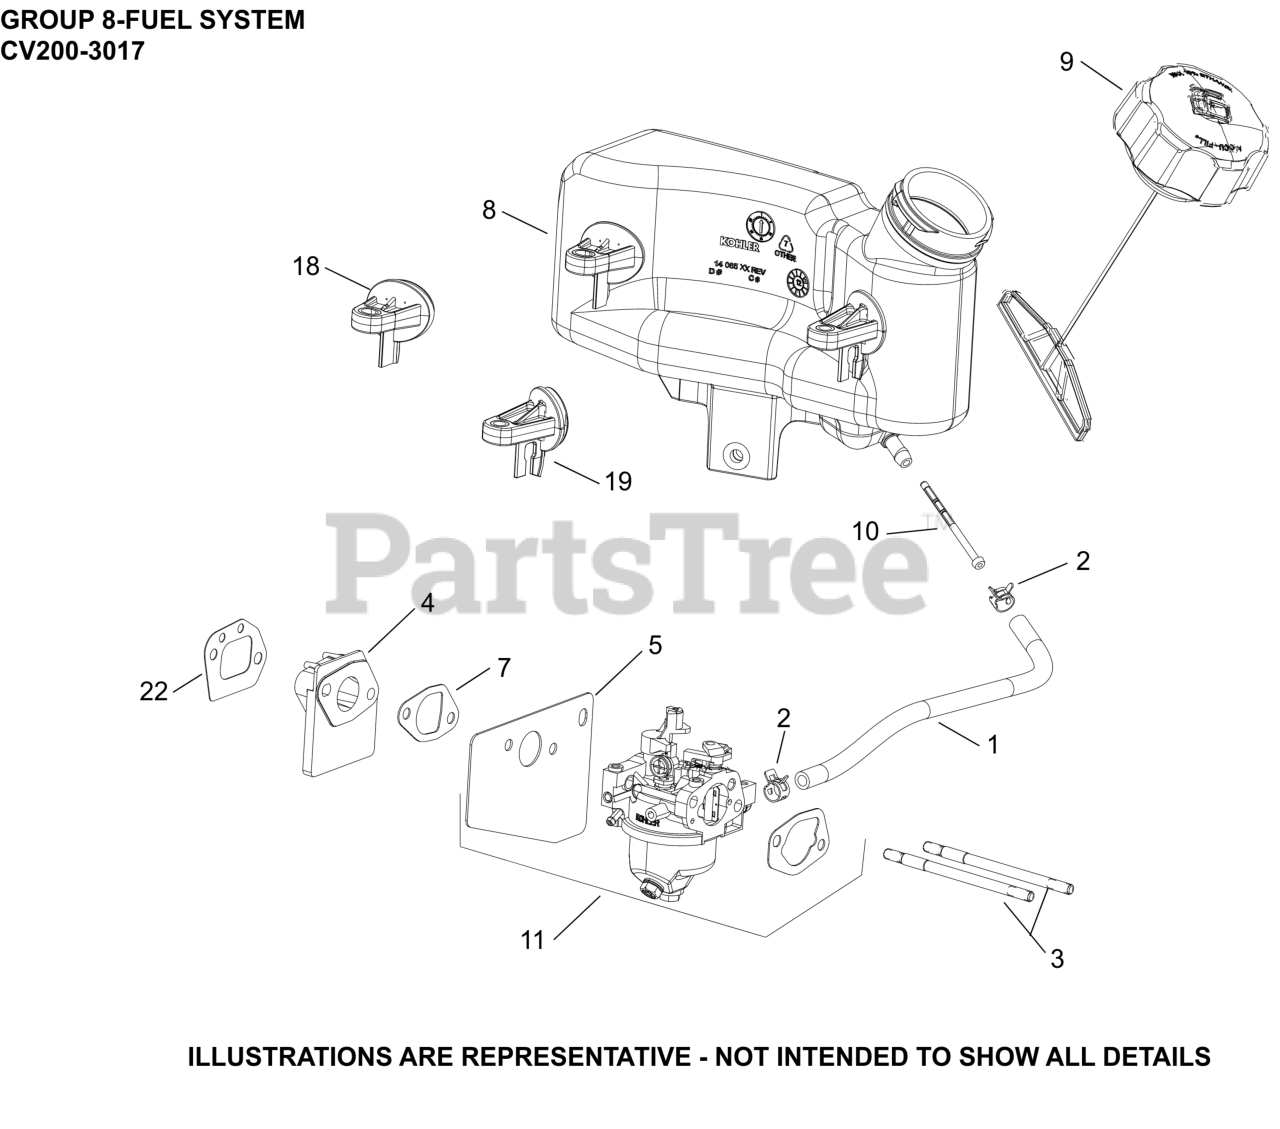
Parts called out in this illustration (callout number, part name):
1	HOSE, FUEL LOW-PERMEATION
2	CLAMP, HOSE (NON-CALIF)(#1423710S)
3	STUD,M6X1.0X100.2MM
4	KIT, SPACER
5	KIT, CARBURETOR HEAT SHIELD GASKET
7	KIT, INTAKE GASKET
8	TANK, FUEL
9	FUEL CAP ASSEMBLY
10	FILTER, FUEL IN-NIPPLE
11	KIT, CARBURETOR COMPLETE
18	BRACKET, FUEL TANK-DISCONTINUED
19	BRACKET, FUEL TANK-DISCONTINUED
22	GASKET SPACER
NI	KIT, HIGH ALTITUDE (4,000 - 8,000 FT)
NI	KIT, CARBURETOR REPAIR (RUIXING)
